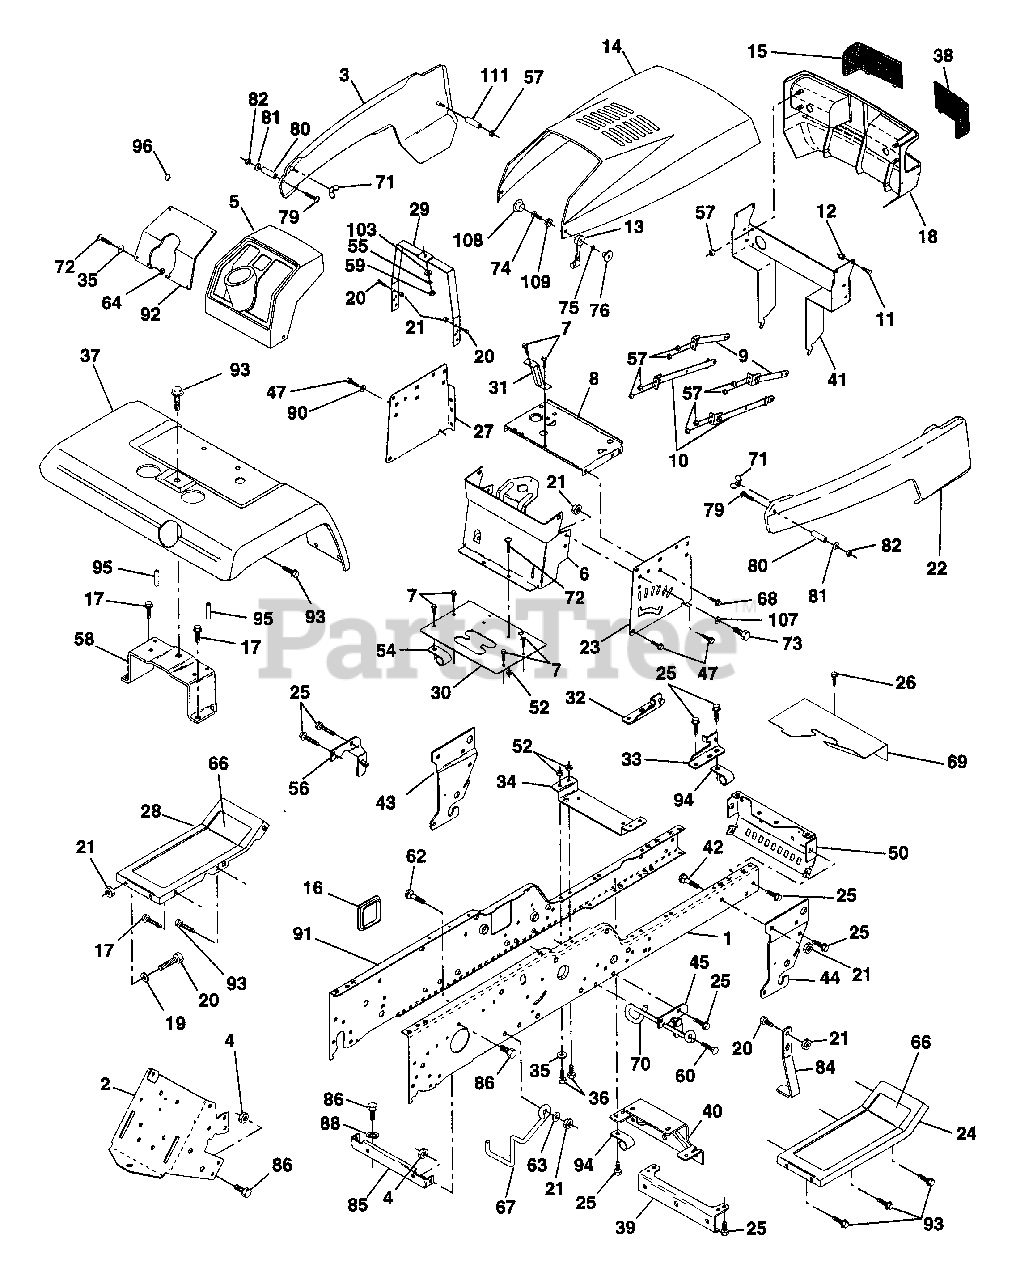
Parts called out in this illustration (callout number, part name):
1	Rail, Frame RH
2	Drawbar, Gt
3	Panel Asm., Side LH
4	Nut, Lock Hex 7/16 Unc
5	Dash, Plastic Black
6	Dash Asm., Lower
7	Screw, Thd Cut 1/4-20 x 1/2
8	Support, Battery
9	Strap, Asm. Hinge Front
10	Strap, Asm. Hinge Rear
11	Bolt Shoulder 1/4-20
12	Nut, Lock W/Ins 1/4-20
13	Latch, Chute Blk
14	Hood Asm., Pnt
15	Lens, Headlight LH
16	Cover, Access
17	Screw, Thdrol 3/8-16 x 3/4
18	Grille
19	Washer 13/32 x 13/16 x 12 Ga.
20	Bolt, Fin Hex 3/8-16 x 1
21	Nut, Lock Hex W/Wsh 3/8-16 Unc
22	Panel Asm., Side RH
23	Panel, Dash Side RH
24	Footrest, RH
25	Screw, Thdrol 3/8-16 x 3/4
26	Screw, Thdrol 5/16-18 x 3/4
27	Panel, Dash Side LH
28	Footrest, LH
29	Bracket, Support Dash
30	Saddle, Slkscr Vgt
31	Brace, Support Steering
32	Bracket Asm., Frame Pivot Lh
33	Bracket Asm., Frame Pivot Rh
34	Bracket, Engine Support Rear
35	Washer 11/32 x 11/16 x 16 Ga.
36	Bolt, Fin Hex 5/16-18 x 3/4
37	Fender, Pnt.
38	Lens Headlight RH
39	Bracket, Axle Front
40	Bracket, Support Axle/Engine
41	Support Asm. Grille
42	Bolt, Carriage 3/8-16 x 1
43	Bracket, Spnsn Front Lh
44	Bracket, Spnsn Front Rh
45	Bracket Asm., Susp Chassis Rh
47	Screw Thdrol 3/8-16 x 1/2
50	Bracket, Chassis Front
52	Locknut, Hex W/Ins 5/16-18 Unc
54	Clip, Insulated
56	Bracket Asm., Susp Chassis Lh
58	Bracket Asm., Fender
59	Nut, Fin Hex 1/4-20
60	Screw Thdrol 3/8-16 x 1-1/4
62	Bolt, Carriage 3/8-16 x 1 Gr. 5
63	Washer 13/32 x 3/4 x 14 Ga.
64	Nut 5/16-18
66	Pad, Footrest
67	Guide, Belt
68	Screw, Thdrol 5/16-18 x 1/2
69	Shield, Heat
70	Guide, Belt Mid Span
71	Nut, Plastic Locking Wing 1/4-20
72	Screw, Mach Trhd 5/16-18 x 3/4
73	Bolt, Fin Hex 3/8-16 x 1 Gr. 5
74	Screw, Machine #10-24
75	Washer, Lock #10
76	Nut, Weld #10-24
79	Screw, Machine #10-24 x 1/4
80	Spacer, Split
81	Washer 7/32 x 1/2 x 18 Ga.
82	Nut #10-24
84	Stop, Over Center Mower
85	Bracket, Support
86	Bolt, Fin Hex 7/16-14 Unc x 1
88	Washer, Lock Hvy Hld Sp 7/16
90	Washer, Lock External Tooth 3/8
91	Rail, Frame Lh
92	Plate, Silkscreen Dash
93	Screw, Thdrol 3/8-16 x 1/2
94	Clip, Fuel Line
95	Push Nut, Nylon
96	Plug, Hole
103	Washer, Lock 1/4
107	Washer 13/32 x 1 x 14 Ga.
108	Cap, Snap Black
109	Cap, Washer Snap
